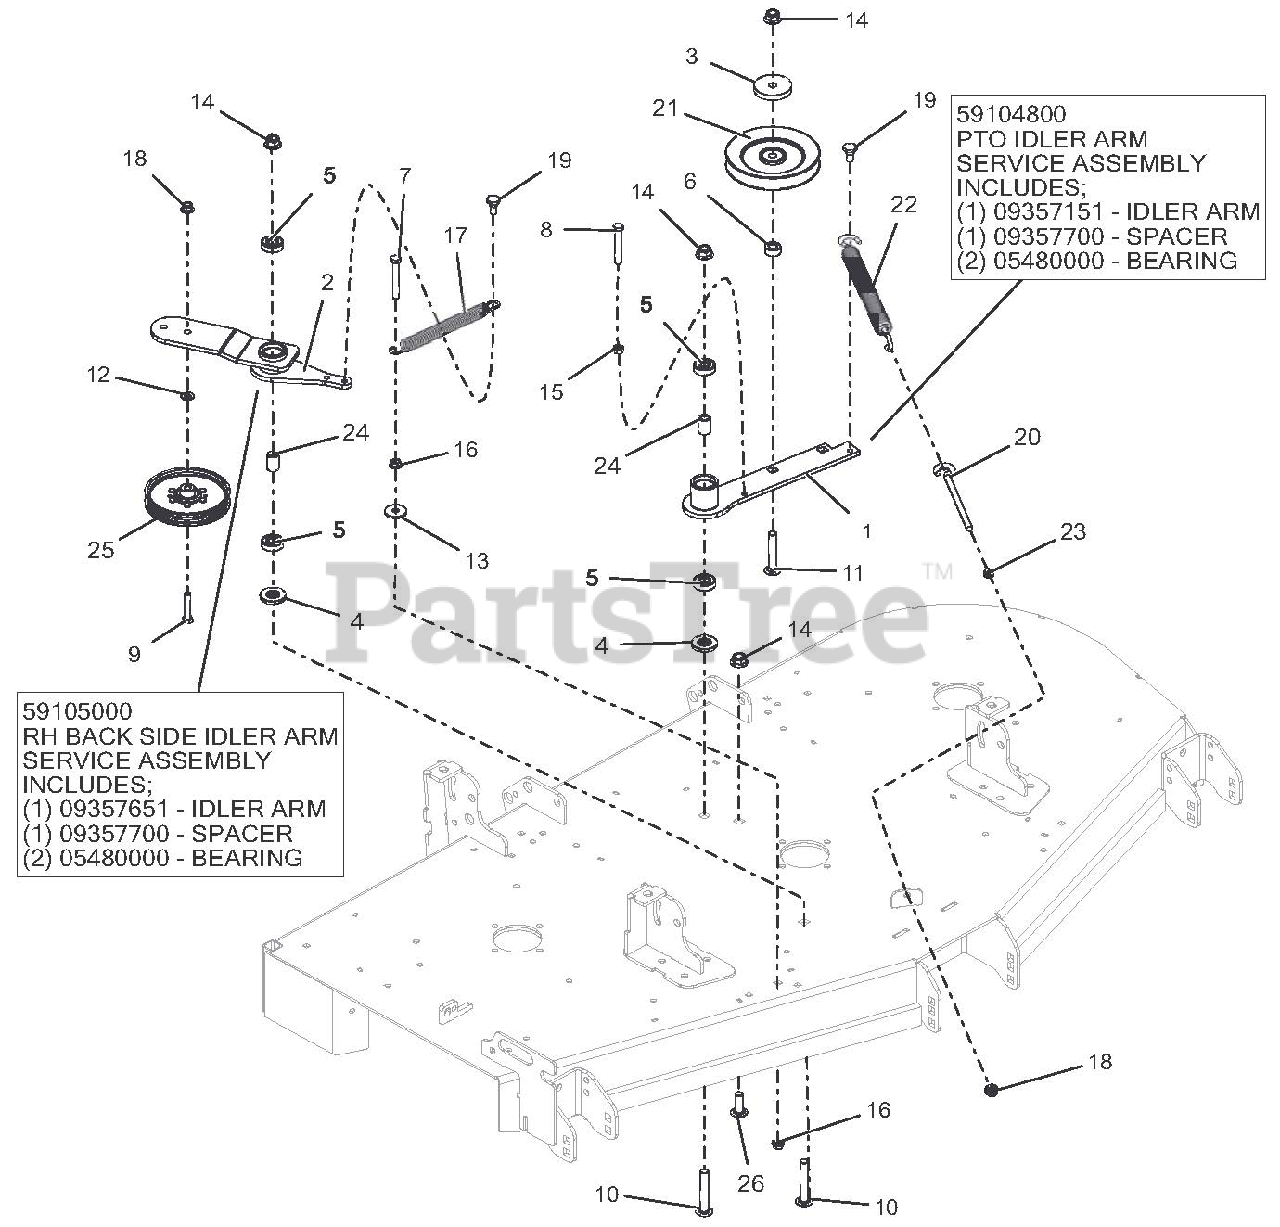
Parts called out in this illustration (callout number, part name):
1	WLDMT, DECK PTO IDLER ARM-BLACK
1	PTO IDLER ARM SERVICE ASSEMBLY
1	IDLER ARM
1	SPACER
1	BEARING
2	WLDMT, DECK RH IDLER ARM
2	RH BACK SIDE IDLER ARM SERVICE ASSEMBLY
2	IDLER ARM
2	SPACER
2	BEARING
3	CAP, IDLER BEARING SEALING
4	SPACER, IDLER ARM
5	BRG-BALL .500X1.375X.44
6	BSHG, SPCR .502 X .997.50 PM
7	BLT-HEX .38-16X3.00 GR5 YWZC
8	BLT-HEX .38-16X2.75 GR5 YWZC
9	BLT-HEX .38-16X2.00 GR5 YWZC
10	BLT-RDHDSQSHNK .50-13X3.25 YWZC
11	BLT-RDHDSQNK .50-13X3.00 G5 Y
12	WSHR-FL-STL.406X.812X.065 YWZ
13	WSHR-FL-STL .406X1.375X.135 YZ
14	NUT-LK-NYL-FLG .50-13 YWZC
15	NUT-HEX .38-16 YWZC
16	@NUT-SPNLK-FLG .375-16 YWZC
17	SPRG, EXTENSION .120X.845X6.55 WLD
18	NUT-LK-NYL-FLG .38-16 YWZC
19	BLT, SHLDR EP .38-16X.30 HEX YZ
20	BOLT, .38-16X6.00 .62 DIA EYE
21	SHEAVE, .50" ID X 6.00" OD V-IDLER
22	SPRG, EXTENSION
23	NUT, JAM .375-16 YWZC
24	SPACER, .510 X .750 X 1.148
25	PULLEY, FLAT IDLER .500 X .375 W/BRG
26	BLT-RDHDSQSHNK .50-13X1.50 YWZC
